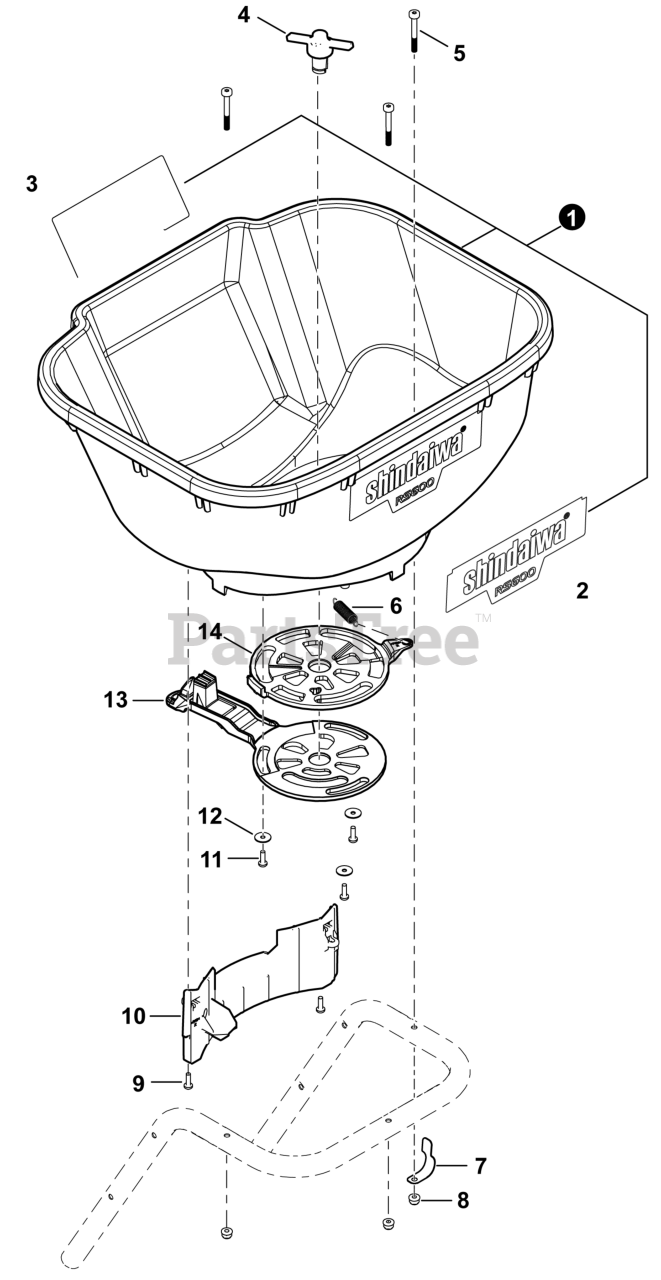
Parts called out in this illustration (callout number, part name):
2	LABEL - SHINDAIWA
3	LABEL - OPERATION
4	AGITATOR
5	BOLT, M6 X 50MM
8	NUT, FLANGE M6
9	BOLT, TORX 5x16
10	COVER, BRACKET
11	BOLT, TORX 5x20
13	METERING PLATE , LOWER
14	METERING PLATE , UPPER
